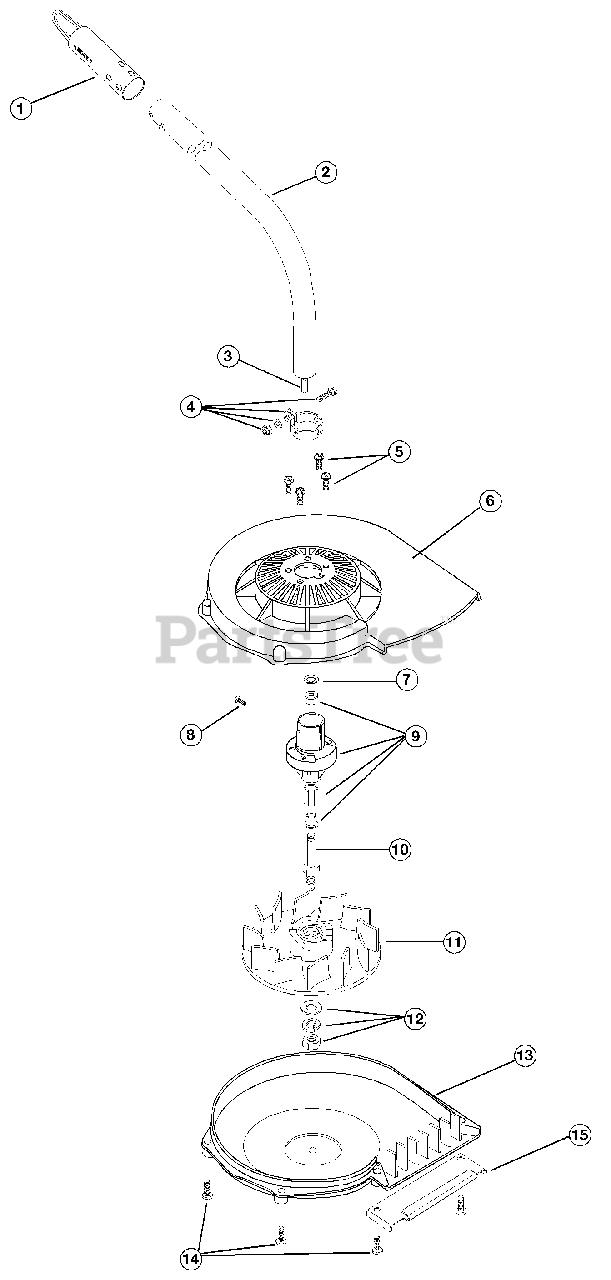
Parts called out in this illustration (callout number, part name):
1	Hanger
2	Drive Shaft Housing Assembly
3	Drive Shaft Assembly
4	Lower Clamp Assembly
5	Mounting Screw Assembly
6	Upper Housing Assembly
7	Palnut
8	Anti-Rotation Screw
9	Bushing Housing Assembly
10	Impeller Shaft
11	Impeller
12	Nut and Washer Assembly
13	Lower Housing Assembly
14	Mounting Screw Assembly
15	Edge Guard
